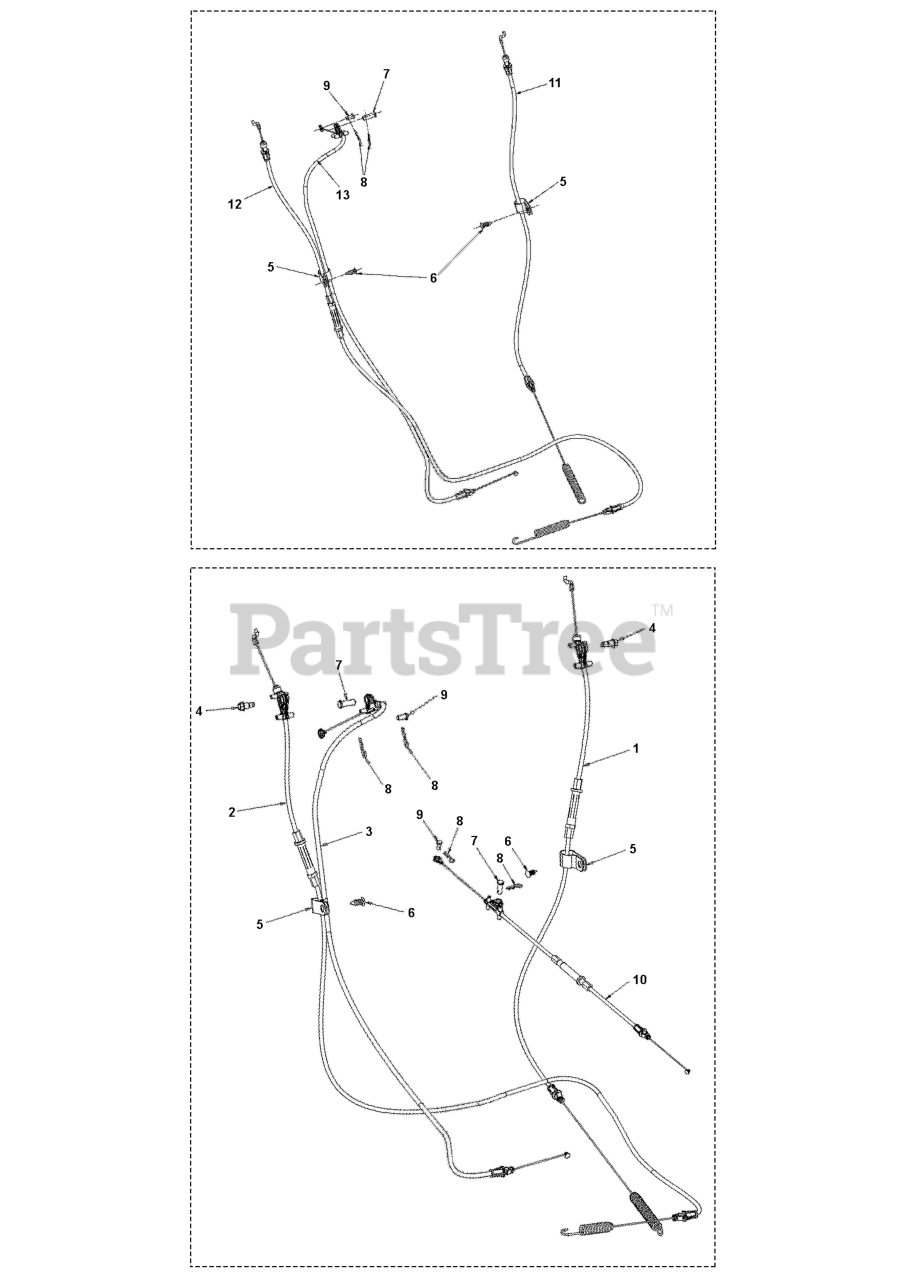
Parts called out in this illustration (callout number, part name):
1	CABLE.CONTROL.DRIVE.DSST.OPP
2	CABLE.CONTROL.AUGER.DSST.OPP.M
3	CABLE.CONTROL.SPEED.DSST.OPP
4	BOLT SHOULDER_1/4-20_TRILOB
5	CLIP.CABLE.BLK
6	FASTENER.PUSH.O.250X0.783
7	PIN CLEVIS 5/16X.875
8	HAIRPIN.SOFT.ZINC.059X1.125
9	PIN CLEVIS .25 X .31
10	RB CABLE.CNTRL.SPEED.DSST.OPP
11	CABLE.DRIVE CONTROL W/ADJ
12	CABLE.CONTROL.AUGER
13	Cables
13	CABLE.CONTROL.SPEED.DSST.OPP
